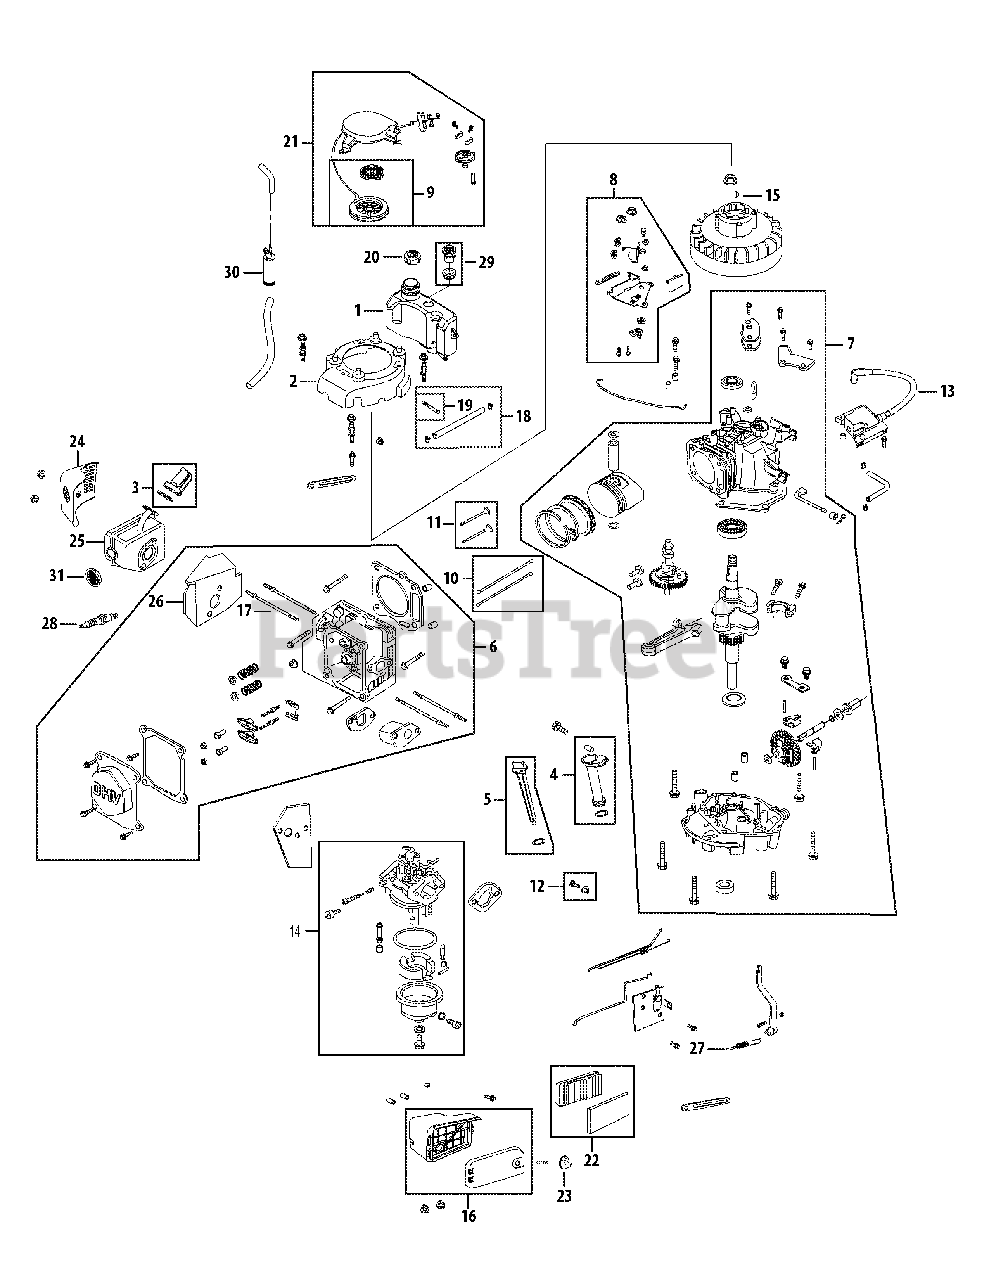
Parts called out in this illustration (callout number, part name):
2	Flywheel Shroud
3	Reed Valve Assembly
4	Oil Filler Tube Assembly
5	Dipstick Assembly
6	Cylinder Head Complete
7	Short Block Assembly
8	Stop Switch and Brake Assembly
9	Recoil Spring and Pulley Assembly
10	Push Rod Kit
12	Oil Drain Plug and Washer Assembly
13	Ignition Coil
14	Carburetor Assembly
15	Flywheel Key
16	Air Cleaner Housing Assembly Complete
17	Muffler Stud Assembly
18	Fuel Line Kit - Inc. hoses, clamps & filter
19	Fuel Filter
21	Recoil Starter Assembly
22	Air Cleaner Kit
23	Air Cleaner Thumb Screw
24	Muffler Guard
26	Muffler Gasket /Heat Shield
27	Governor Return Spring
28	Spark Plug
29	Roll Over Valve Assembly
30	Carbon Canister
31	Spark Arrestor
